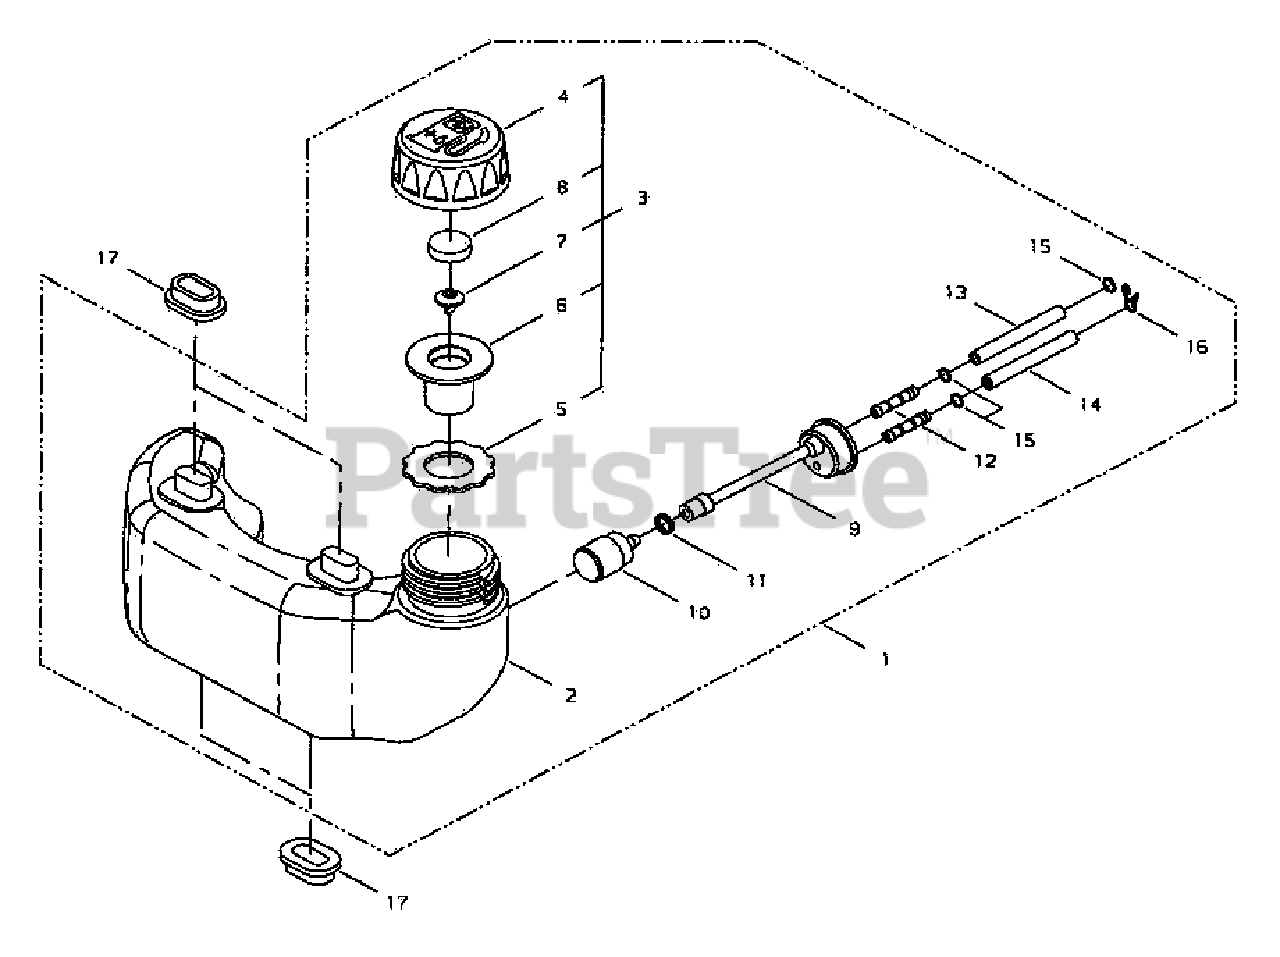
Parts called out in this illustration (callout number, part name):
1	FUEL TANK ASSY
2	TANK, FUEL
3	CAP ASSY
4	CAP ASSY
5	GASKET, CAP
6	VENT, FUEL TANK
7	VENT, FUEL TANK
8	COVER, VENT
9	FUEL PIPE ASSY
10	FILTER, FUEL
11	RING, RETAINING
12	CONNECTOR, PIPE
13	PIPE
14	PIPE - RETURN
15	RING, RETAINING - 6
16	CLIP - SPRING
17	CUSHION, FUEL TANK
